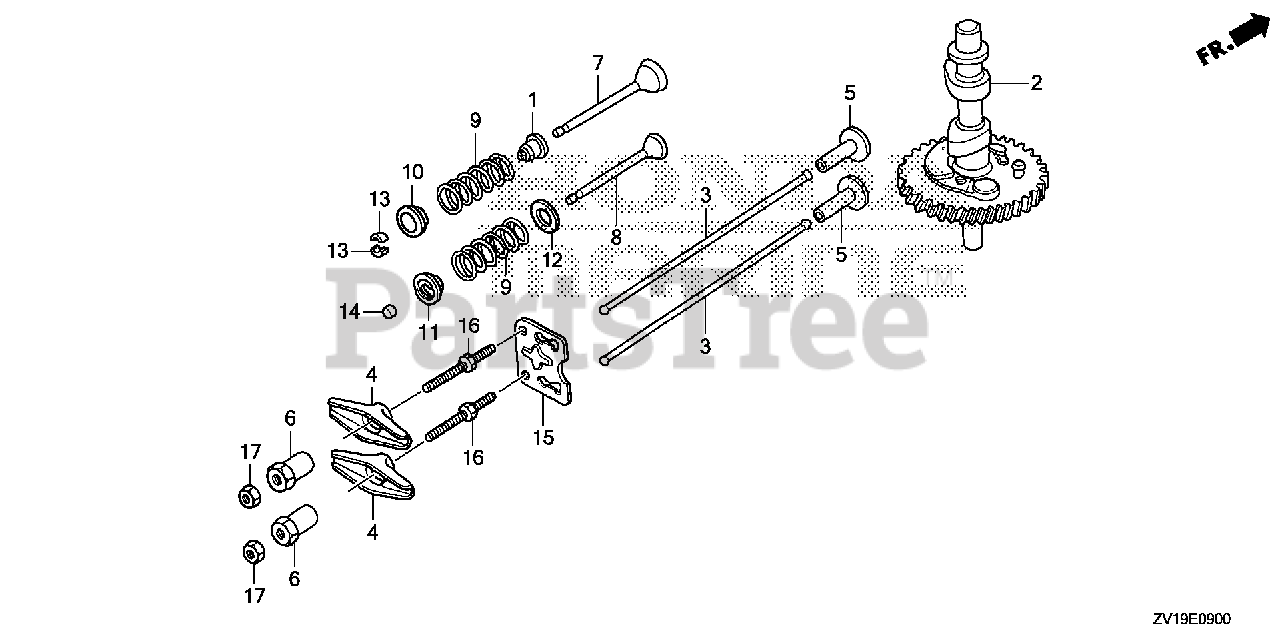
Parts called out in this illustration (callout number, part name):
1	SEAL, VALVE STEM
3	ROD, PUSH
4	ARM, VALVE ROCKER
5	LIFTER, VALVE
6	PIVOT, ROCKER ARM
7	VALVE, IN.
8	VALVE, EX.
9	SPRING, VALVE
10	RETAINER, VALVE SPRING
11	RETAINER, EX. VALVE SPRING
12	SEAT, VALVE SPRING
13	COTTER, VALVE (SANKO)
14	ROTATOR, VALVE
15	PLATE, PUSH ROD GUIDE
16	BOLT, PIVOT (8MM)
17	NUT, PIVOT ADJ.
